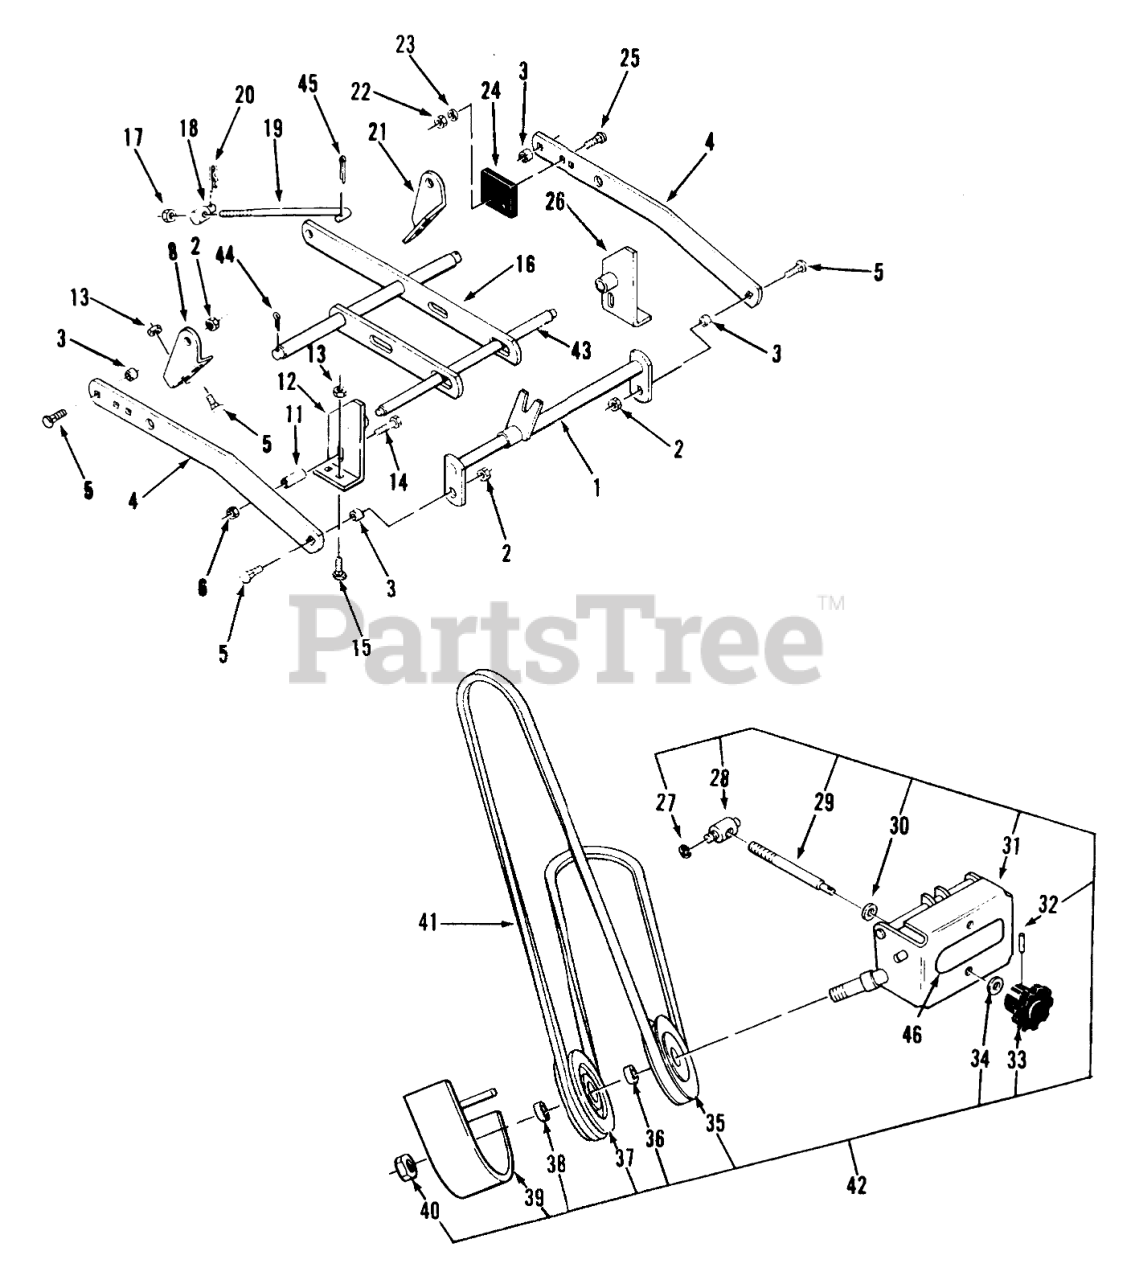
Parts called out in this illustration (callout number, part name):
1	Hitch
2	LOCKNUT-FLANGE
3	SPACER
4	Bar Draft
5	BOLT-CARR
6	Nut
8	Bracket-Rt. Rear
12	Bracket-R.H.
13	NUT-LOCK, NI
14	BOLT-CARR
15	BOLT-CARR
16	Leveler
17	NUT-LOCK, NI
18	TRUNNION-LIFT
19	Rod-Lift
20	Hairpin
21	Bracket-L.H. Rear
22	NUT-LOCK, NI
23	WASHER-FLAT
24	BUMPER
25	SCREW-CARR
26	Bracket-L.H.
27	RING-RETAINING
28	TRUNNION-DOUBLE
29	ROD ADJ
30	WASHER-FLAT
31	Front Support
32	PIN-ROLL
33	KNOB-ADJUSTMENT
34	WASHER-SPRING
35	Pulley-V
36	SPACER
37	PULLEY-FLAT IDLER
38	SPACER-OUTER
39	Belt Cover
40	Nut
41	V-BELT
42	Front Idler Assembly (Incl. Ref. #27-40, & 46)
43	Front Shaft
44	PIN-COTTER
45	PIN-COTTER
46	Decal-Attac-O-Matic
